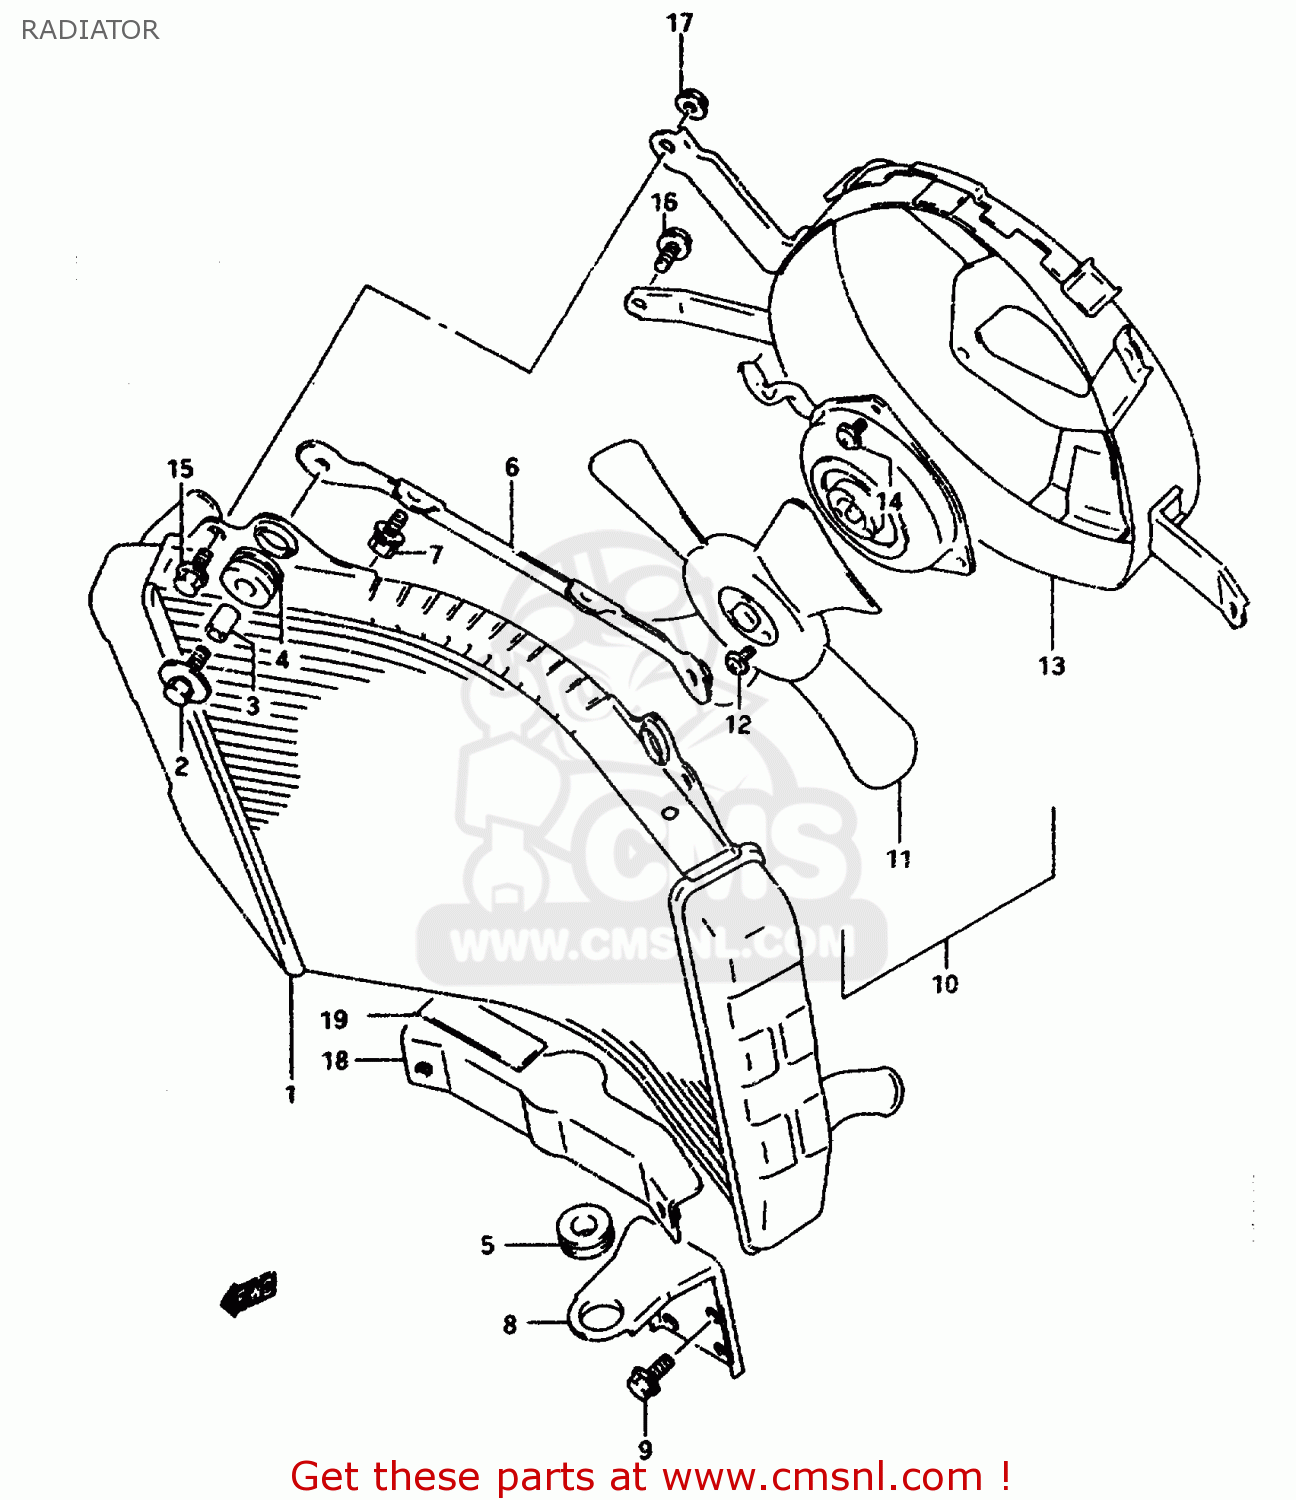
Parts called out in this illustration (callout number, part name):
1	RADIATOR ASSY,WATER
2	BOLT(6X25)
3	SPACER(6.5X10.5X12)
4	CUSHION,RADIATOR LWR
5	CUSHION
6	BRACKET COMP,RADIATOR
7	BOLT
8	BRACKET,RADIATOR,LOWER
9	BOLT
10	FAN ASSY,RADIATOR
11	FAN
12	SCREW 4X6
13	SHROUD
14	SCREW
15	BOLT
16	BOLT
17	NUT
18	BRACKET,RADIATOR,LOWER,NO
19	CUSHION(50X42X2.0)
